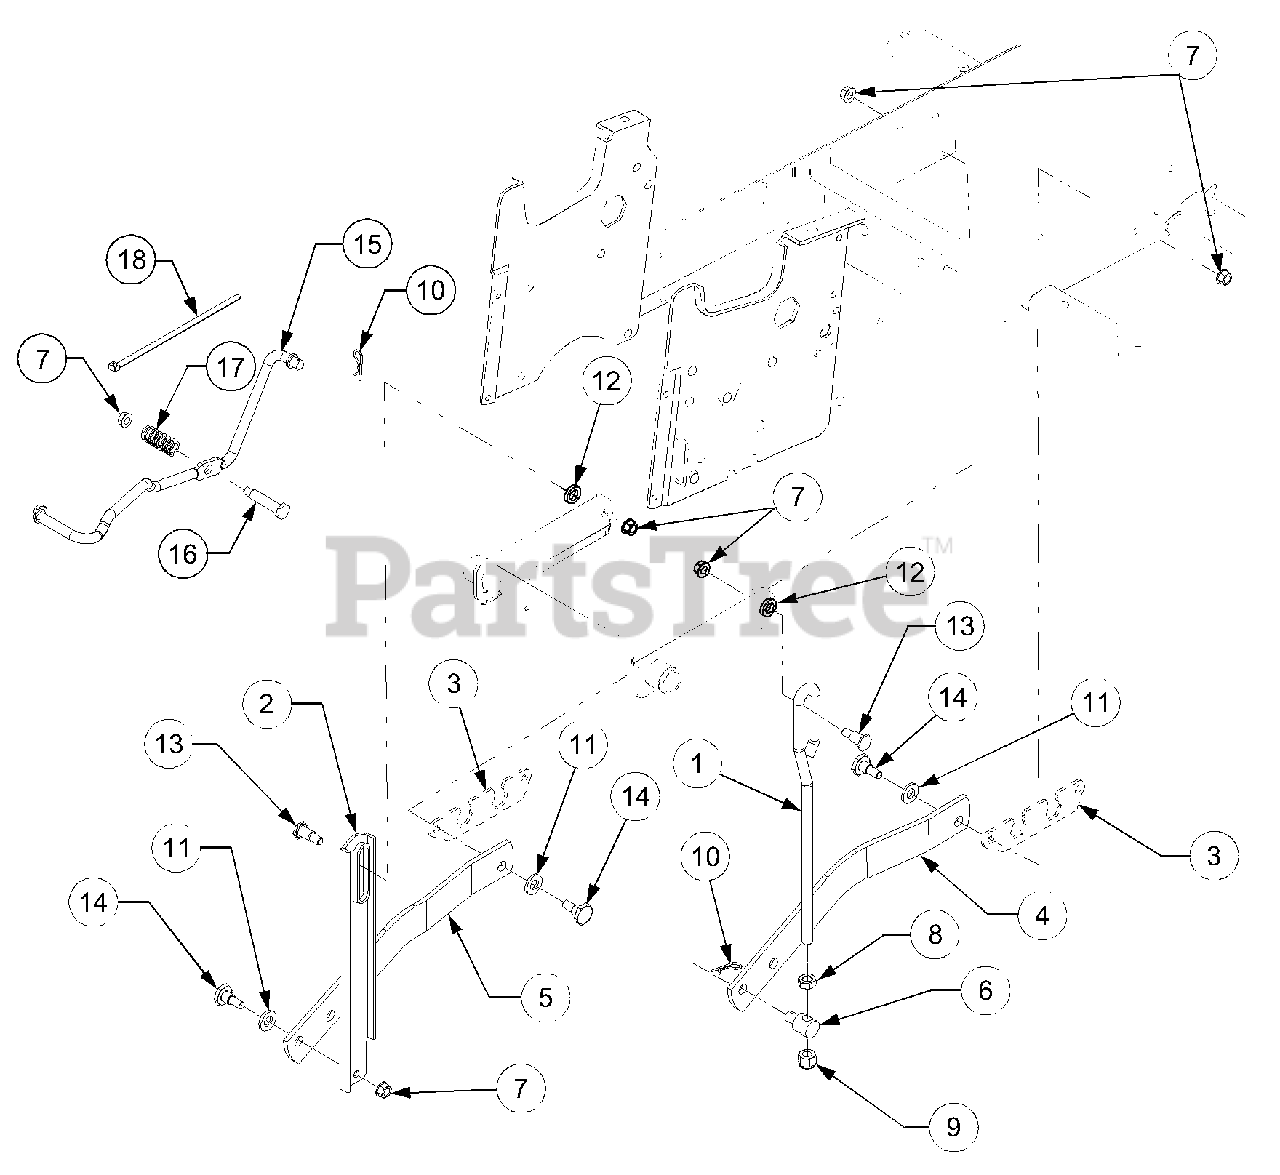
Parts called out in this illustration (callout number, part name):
1	Rod, Lift Link
7	Nut, Hex Flange Lock, 3/8-16
8	Nut, Hex Jam, 1/2-13 GR5
9	Nut, Hex Insert Lock, 1/2-13
10	Pin, Internal Cotter
11	Washer, Flat, .5 x 1.5 x .15
12	Washer, Flat, .531 x .875 x .15
13	Bolt, Shoulder
14	Bolt, Shoulder
15	Rod, Lift Assist
16	Bolt, Shoulder, 3/8-16: .5 x 2.0
17	Spring, Compression, .63 ID x 2.0
18	Tie, Cable
